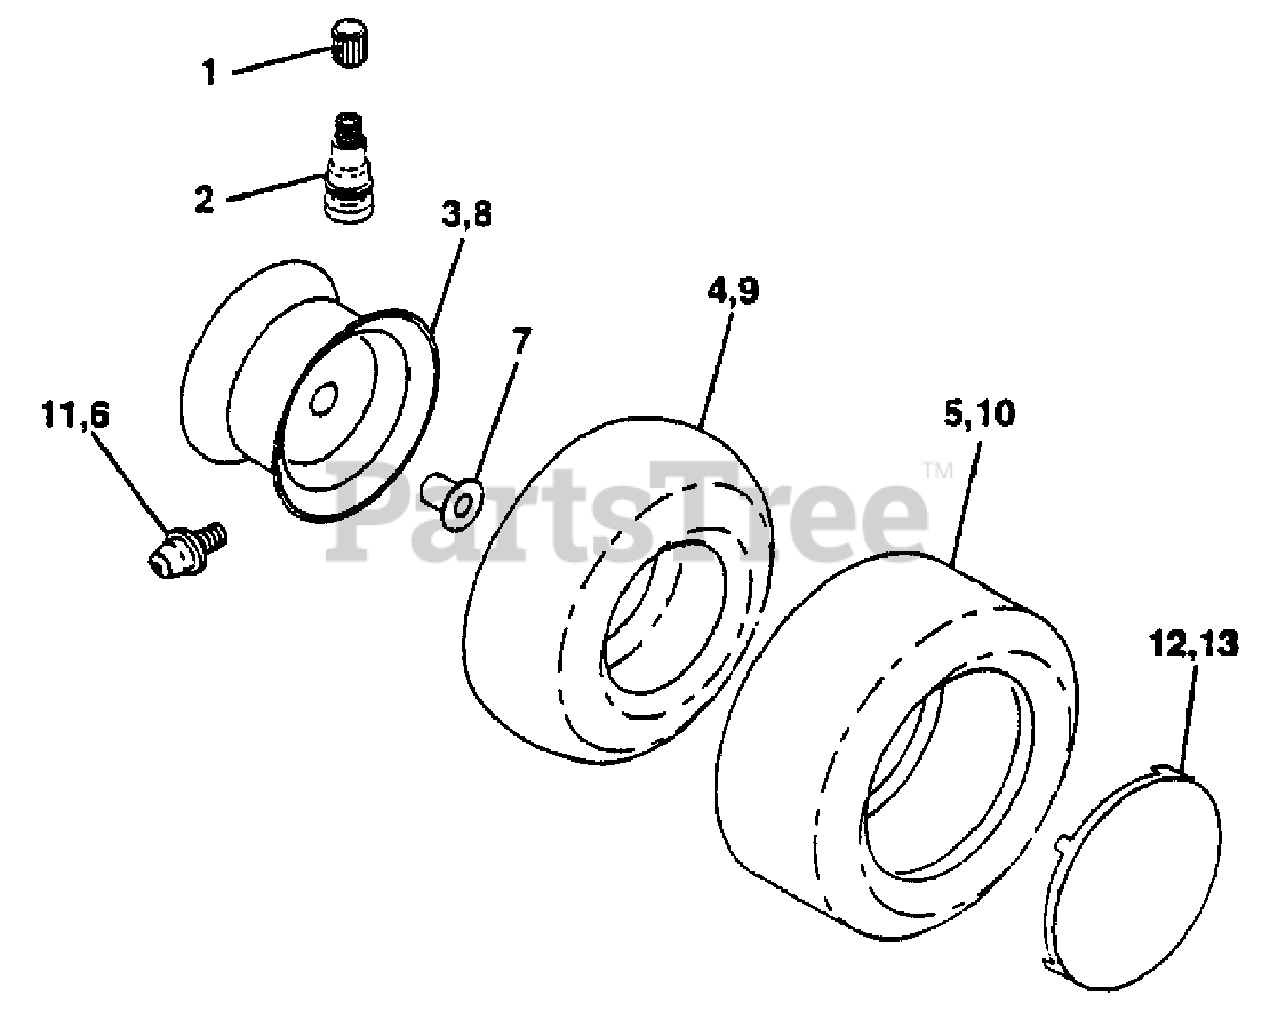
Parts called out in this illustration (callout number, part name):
1	Cap, Valve, Tire
2	Stem, Valve
3	Rim Assembly, Front
4	Tube, Front
5	Tire, Front
6	Fitting, Grease
7	Bearing, Flange
8	Rim Assembly, Rear
9	Tube, Rear
10	Tire, Rear
11	Fitting, Grease
12	Cover Wheel 8" White
13	Cover, Wheel 12" White
